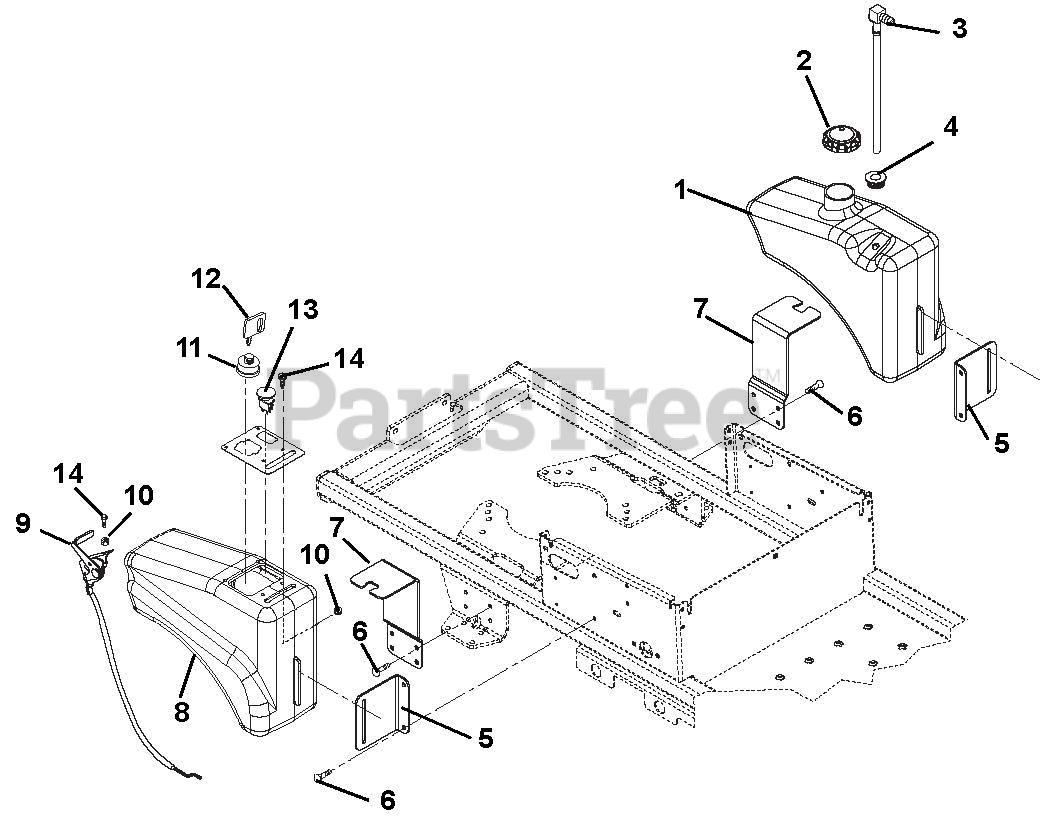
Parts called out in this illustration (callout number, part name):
1	Tank, Fender - Left Hand
2	Fuel Cap
3	Fitting, Tank
4	Bushing, Flange .375 x 1.062 x .625
5	Bracket, Fuel Tank
6	Screw, Tapping .31-18 x .50
7	Mount, Fuel Tank
8	Tank, Fender - Right Hand
9	Cable, Throttle
10	Nut-Locking-Nylon 10-24 with Insert
11	Key Switch
12	Key, w/cap
13	Switch, Clutch
14	Screw-Machine 10-24 x .75 Hex Washer Head
15	Control Panel
